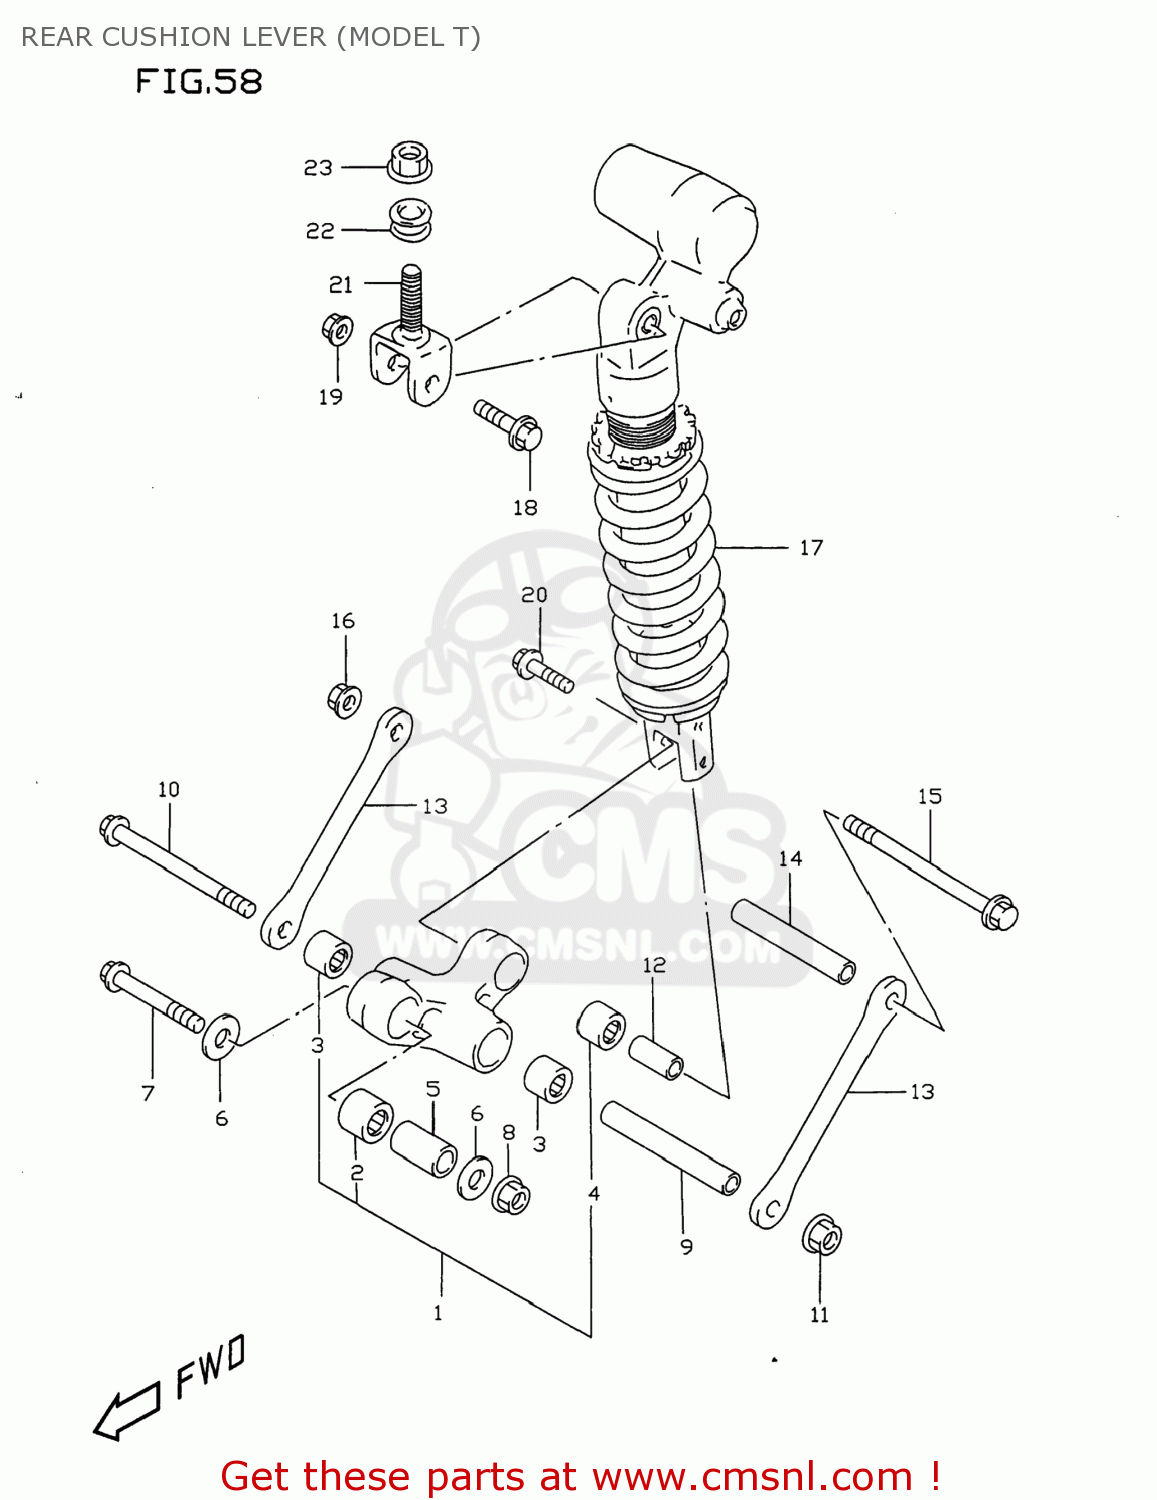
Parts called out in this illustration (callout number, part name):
1	LEVER SET,RR CUSHION
2	BEARING(20X27X30)
3	BEARING(17X24X20)
4	BEARING(17X24X26)
5	SPACER,RR CUSHION LEVER FR
6	WASHER
7	BOLT,RR CUSHION LEVER FR
8	NUT 12MM
9	SPACER,RR CUSHION LEVER CTR
10	BOLT,RR CUSHION LEVER CTR
11	NUT 12MM
12	SPACER,RR CUSHION LEVER
13	ROD,RR CUSHION LEVER
14	SPACER,RR CUSHION LEVER CTR
15	BOLT,RR CUSHION LEVER CTR
16	NUT 12MM
17	ABSORBER ASSY,RR SHOCK
18	BOLT(10X54)
19	NUT
20	BOLT(10X44)
21	BRACKET,RR SHOCK ABSORBER UPR
22	SPACER,RR SHK ABS BRACKET
23	NUT
